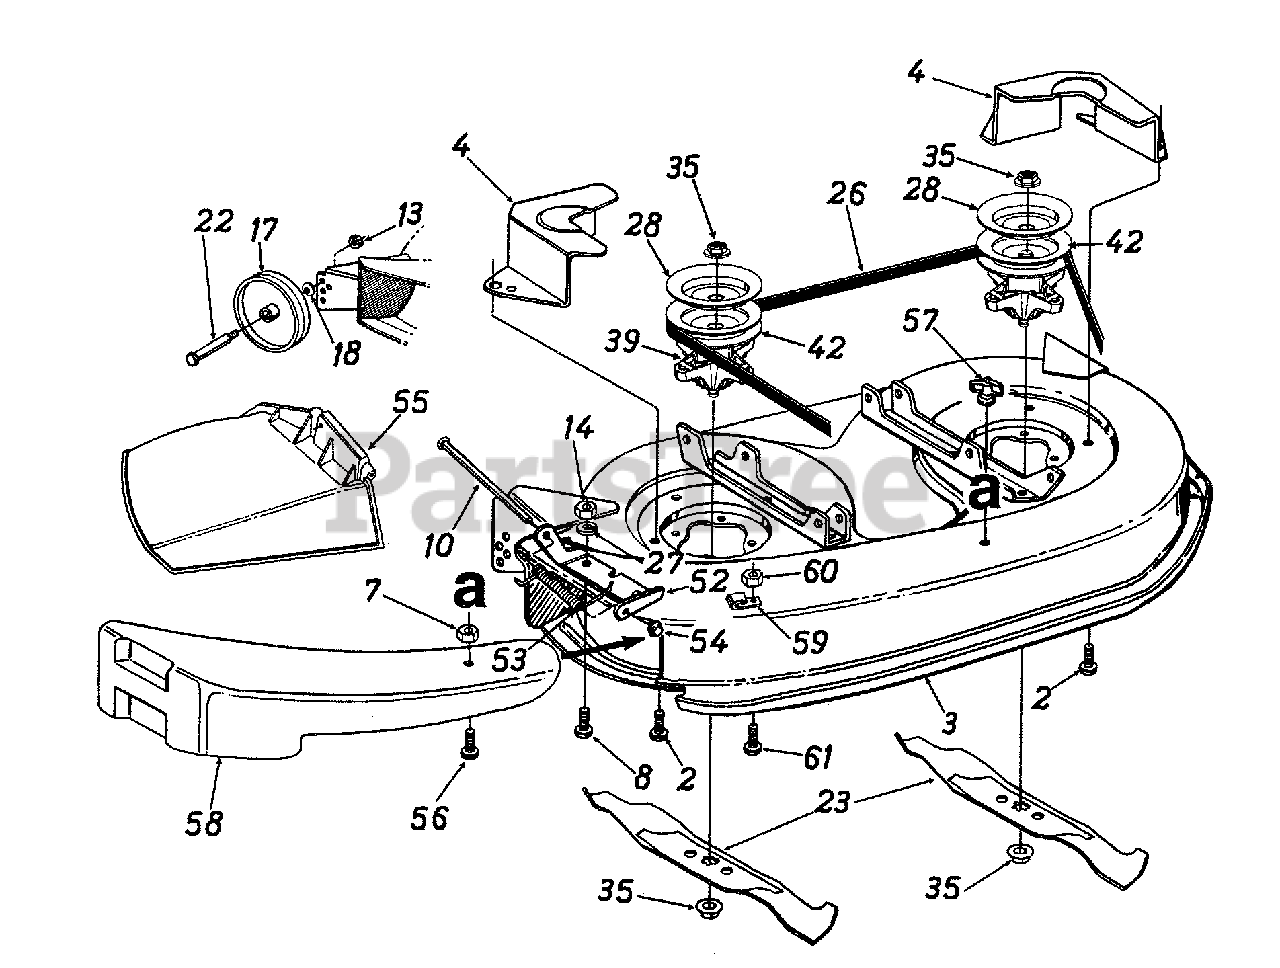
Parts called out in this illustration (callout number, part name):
2	Hex Washer: TT-Tap Scr. 5/16-18 x .75" Lg.
7	Hex Lock Nut 1/4-20 Thd.
8	Hex Bolt 1/4-20 x .62"
10	Hinge Pin
13	Hex Top Lock Nut 3/8-16 Thd.
14	Hex Nut 1/4-20 Thd. Gr. 5
17	Deck Wheel 5"
18	Bell Washer 0.40" I.D. x .88" O.D.
22	Shoulder Bolt .498" Dia. x 1.53"
23	3 in 1 Star Blade
26	V-Belt
27	Bell Washer 1/4" I.D.
28	Brake Disc
35	Hex Flange Nut 5/8-18 Thd.
39	Blade Spindle Ass'y.
42	5" Dia. Deck Pulley
52	Hinge Mtg. Bracket
53	Torsion Spring
54	Push Nut
55	Chute Ass'y. Comp.
56	Hex Bolt 1/4-20 x 1" Lg.
57	Wing Nut 1/4-20 Thd.
58	Mulching Plug
59	Retainer Hook Bracket
60	Hex Sems Nut 1/4-20 Thd.
61	Hex Bolt 1/4-20 x .62" Lg.
